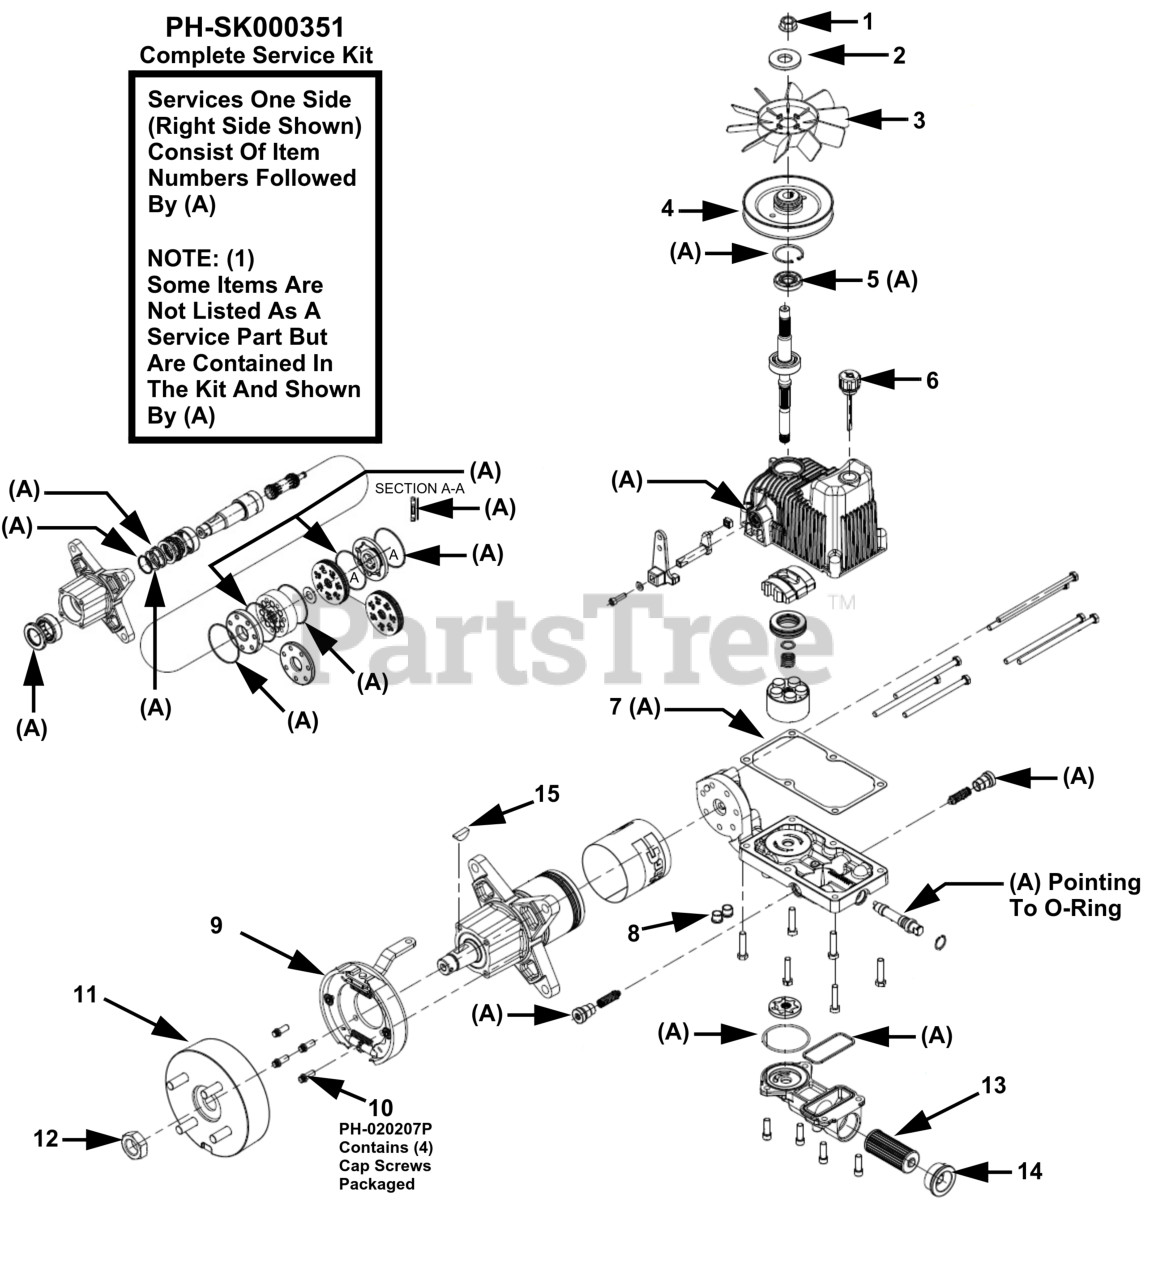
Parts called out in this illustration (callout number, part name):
1	NUT-FLANGE 1/2-20
2	FAN SPACER
4	PULLEY (SPLINED)
6	BREATHER
8	PLUG-MAGNETIC HEX
9	BRAKE ASSEMBLY-ON HOLE LEVER
10	SCREW-CAP (QTY 4)
11	DRUM-4 BOLT BRAKE
12	LOCK NUT - 1-20
14	PLUG & O-RING ASSE
15	WOODRUFF KEY
16	ROTATING BRACKET
A	COMPLETE SEAL SERVICE KIT
